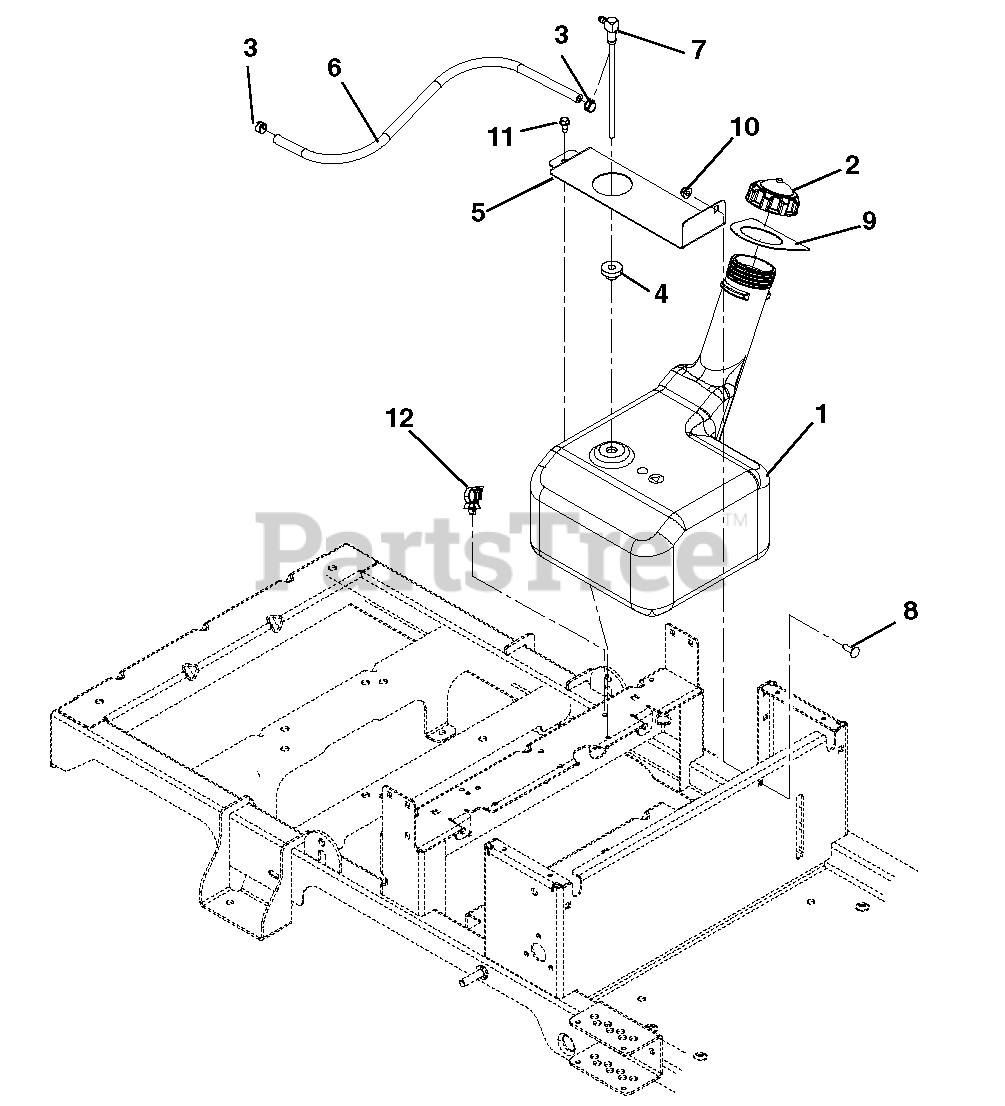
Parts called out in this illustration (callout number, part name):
2	Fuel Cap
3	Clamp, Fuel Line
5	Bracket, Tank Strap
6	Hose, .25 Low Perm Gas 10in.
7	Assembly, Fuel Pickup
8	Bolt, Round Head Square Neck .25-20 x .75 Grade 5
9	Seal, Tank Neck
10	Nut, .25-20 Nyloc Flange
11	Screw, Tapping .25-20 x .50 Hex Washer Head
12	Wire Clip
